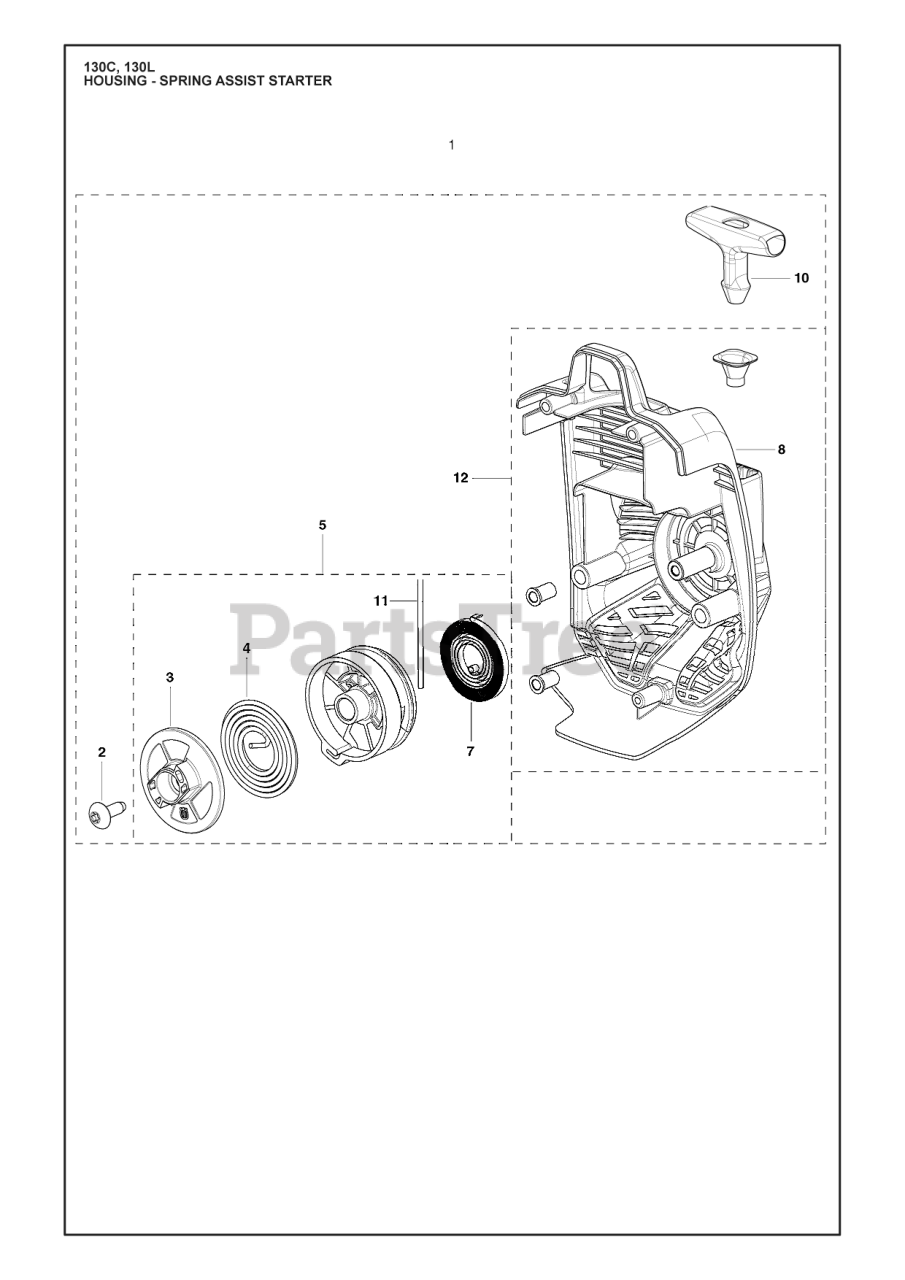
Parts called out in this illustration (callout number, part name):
1	SERVICE KIT 130 TRIMMER START
2	SCREW
3	DRIVER SPRING ASSIST
4	DRIVER SPRING
5	SERVICE KIT 130 TRIMMER START
7	Springs
8	STARTER HOUSING ASSEMBLY
10	STARTER HANDLE
11	KIT ROPE
12	STARTER HOUSING
